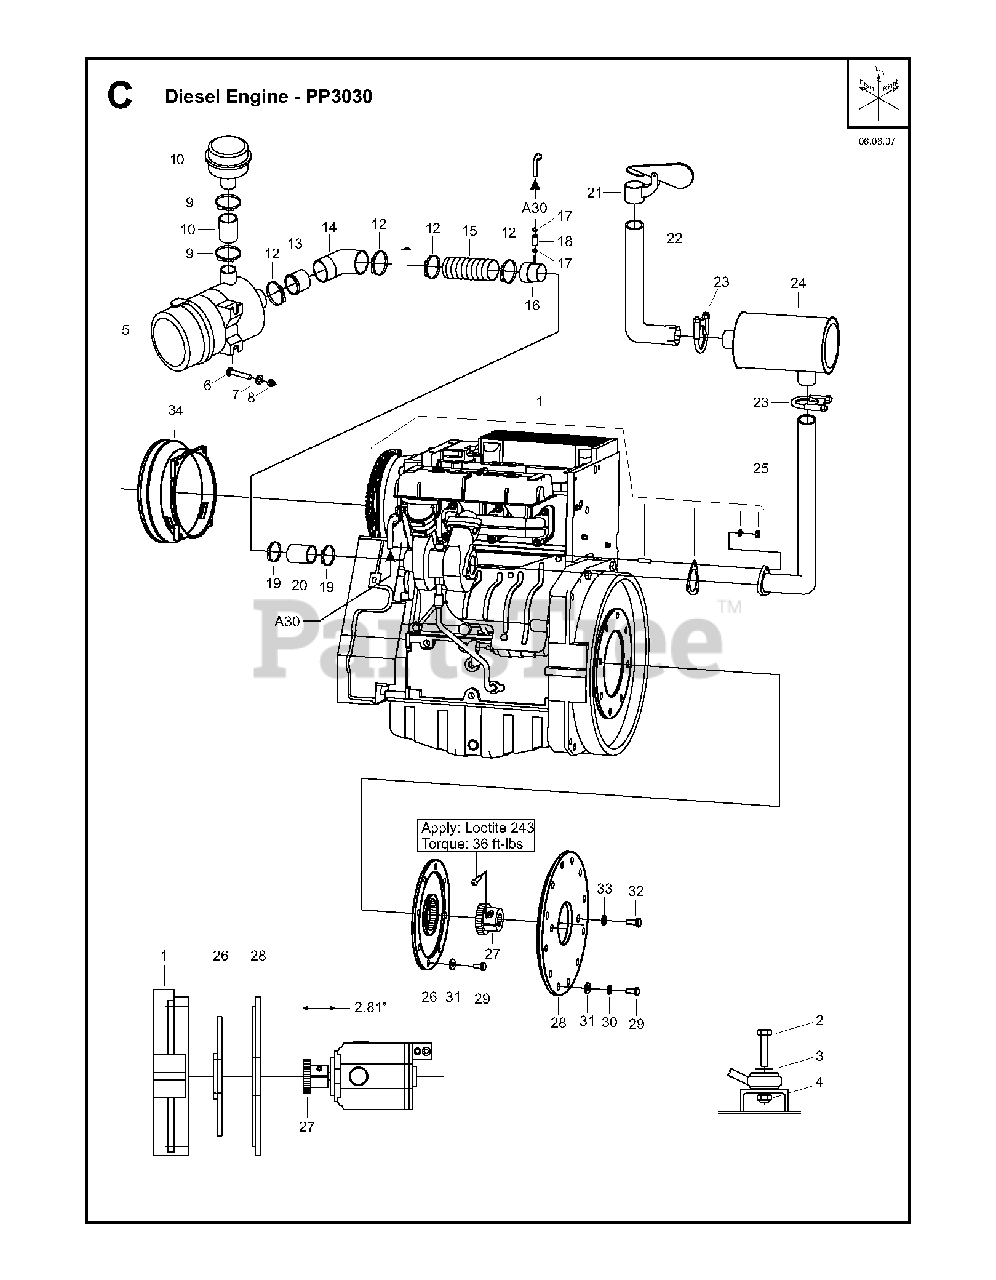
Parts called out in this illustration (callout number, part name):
7	WASHER
8	NUT
18	HOSE, WATER, 1/2" BULK
29	HHCS. M10 x 1.5 x 25 DIN933 ZP
30	LOCKWASHER. SPLIT M10
